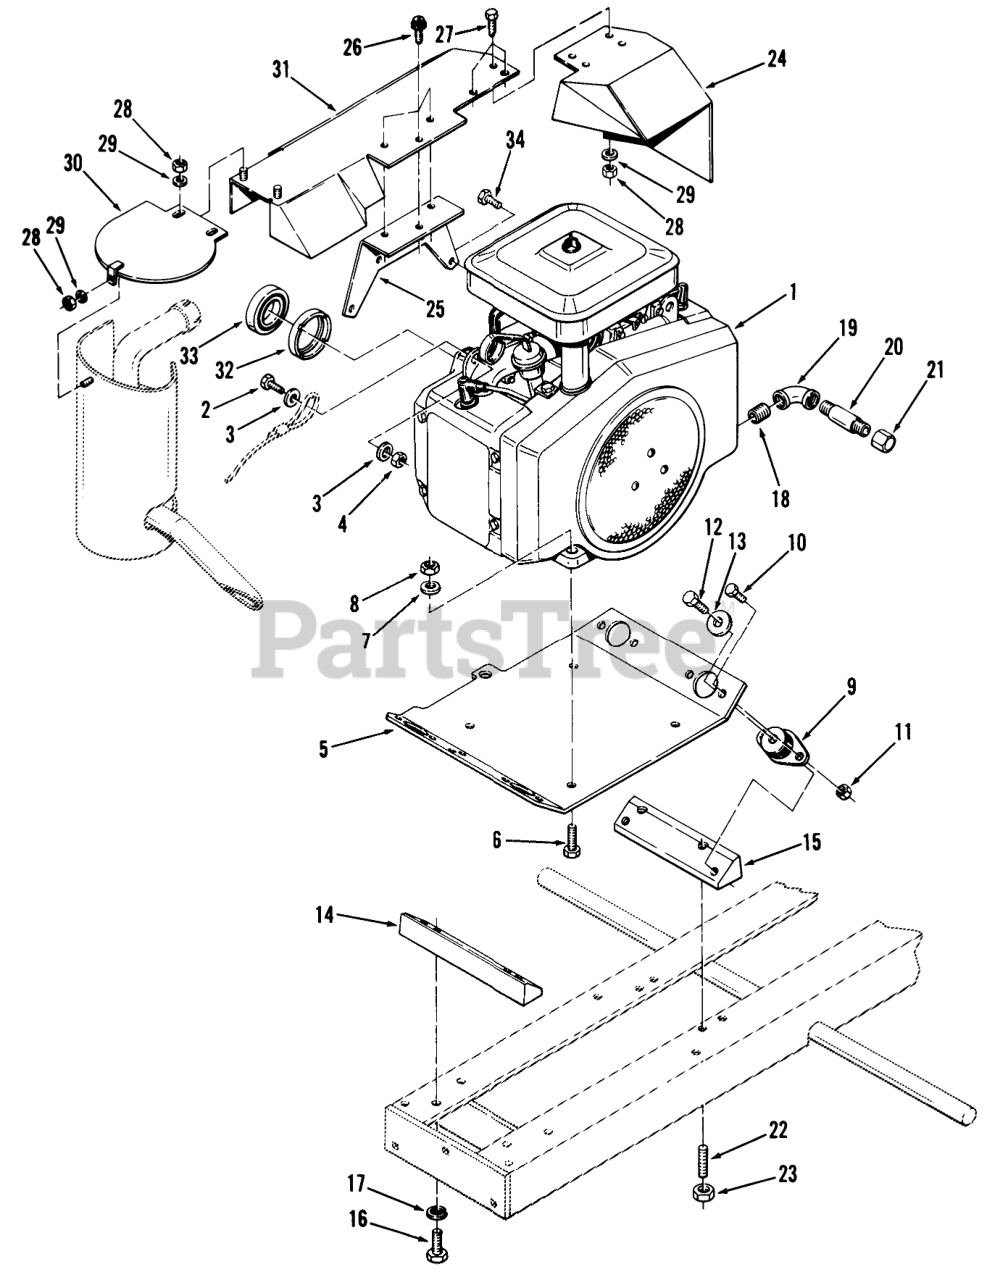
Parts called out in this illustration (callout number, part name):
1	Engine-16HP Briggs & Stratton 401417
2	H H C S
3	WASHER
4	Nut
5	Engine Cradle
6	Bolt
7	WASHER 5/16 SAE
8	Nut
9	Isolation Mount
10	H H C S
11	Nut
12	Bolt
13	Washer
14	Engine Mounting Block-Front
15	MOUNT BLOCK-REAR
16	BOLT
17	LOCKWASHER
18	Nipple 3/8
19	Elbow 3/8
20	Nipple 3/8 X 7
21	Cap
22	SET SRW 3/8X16-1 3/4
23	Nut
24	Rear Heat Shield
25	BRACKET-HEAT SHIELD
26	Washer HD. S.T. Bolt 1/4-20 X 5/8 (Type F)
27	H H C S
28	Nut
30	Muffler Shield
31	HEAT SHIELD ASSY
32	THRUST WASHER
33	BEARING-BALL
34	Bolt
